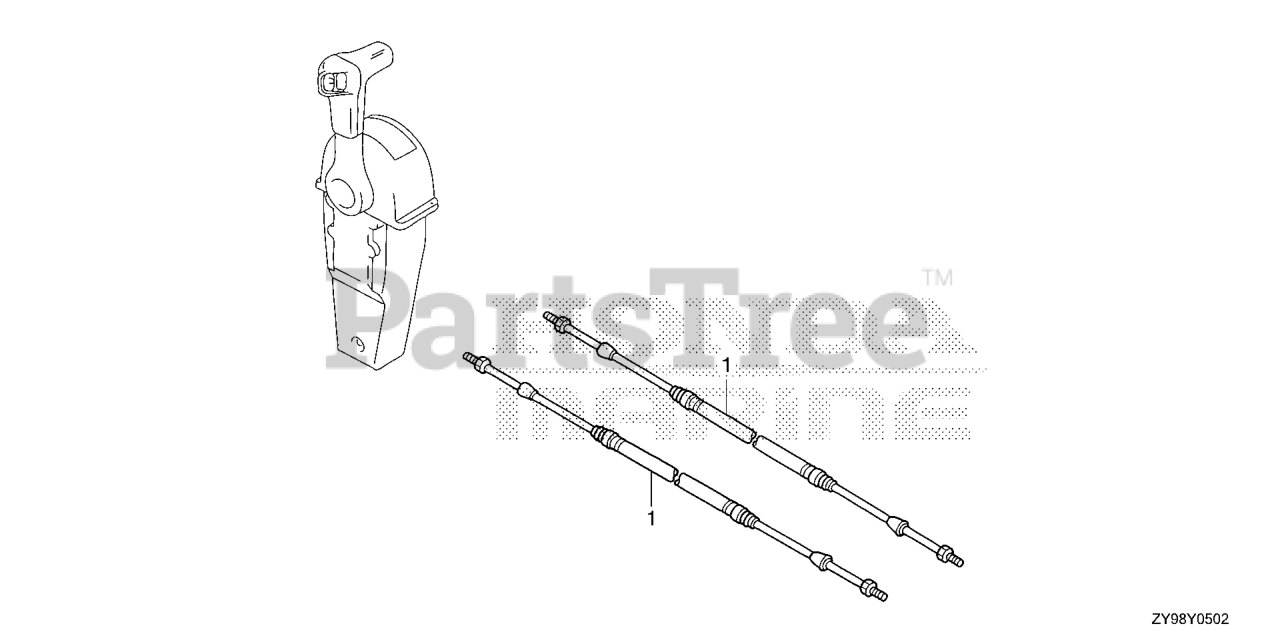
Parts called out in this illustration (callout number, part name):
1	CABLE ASSY., PUSH-PULL (33HPC-5FT)
1	CABLE ASSY., PUSH-PULL (33HPC-6FT)
1	CABLE ASSY., PUSH-PULL (33HPC-7FT)
1	CABLE ASSY., PUSH-PULL (33HPC-8FT)
1	CABLE ASSY., PUSH-PULL (33HPC-9FT)
1	CABLE ASSY., PUSH-PULL (33HPC-10FT)
1	CABLE, REMOTE CONTROL (10') (TELEFLEX)
1	CABLE, REMOTE CONTROL (10') (NOT AVAILABLE)
1	CABLE ASSY., PUSH-PULL (33HPC-11FT)
1	CABLE, REMOTE CONTROL (11') (TELEFLEX)
1	CABLE ASSY., PUSH-PULL (33HPC-12FT)
1	CABLE, REMOTE CONTROL (12') (TELEFLEX)
1	CABLE ASSY., PUSH-PULL (33HPC-13FT)
1	CABLE, REMOTE CONTROL (13') (TELEFLEX)
1	CABLE ASSY., PUSH-PULL (33HPC-14FT)
1	CABLE, REMOTE CONTROL (14') (TELEFLEX)
1	CABLE ASSY., PUSH-PULL (33HPC-15FT)
1	CABLE, REMOTE CONTROL (15') (TELEFLEX)
1	CABLE ASSY., PUSH-PULL (33HPC-16FT)
1	CABLE, REMOTE CONTROL (16') (TELEFLEX)
1	CABLE ASSY., PUSH-PULL (33HPC-17FT)
1	CABLE, REMOTE CONTROL (17') (TELEFLEX)
1	CABLE ASSY., PUSH-PULL (33HPC-18FT)
1	CABLE, REMOTE CONTROL (18') (TELEFLEX)
1	CABLE ASSY., PUSH-PULL (33HPC-19FT)
1	CABLE, REMOTE CONTROL (19') (TELEFLEX)
1	CABLE ASSY., PUSH-PULL (33HPC-20FT)
1	CABLE, REMOTE CONTROL (20') (TELEFLEX)
1	CABLE ASSY., PUSH-PULL (33HPC-21FT)
1	CABLE ASSY., PUSH-PULL (33HPC-22FT)
1	CABLE ASSY., PUSH-PULL (33HPC-23FT)
1	CABLE ASSY., PUSH-PULL (33HPC-24FT)
1	CABLE ASSY., PUSH-PULL (33HPC-25FT)
1	CABLE ASSY., PUSH-PULL (33HPC-26FT)
1	CABLE ASSY., PUSH-PULL (33HPC-27FT)
1	CABLE ASSY., PUSH-PULL (33HPC-28FT)
1	CABLE ASSY., PUSH-PULL (33HPC-29FT)
1	CABLE ASSY., PUSH-PULL (33HPC-30FT)
1	CABLE ASSY., PUSH-PULL (33HPC-31FT)
1	CABLE ASSY., PUSH-PULL (33HPC-32FT)
1	CABLE ASSY., PUSH-PULL (33HPC-33FT)
1	CABLE ASSY., PUSH-PULL (33HPC-34FT)
1	CABLE ASSY., PUSH-PULL (33HPC-35FT)
1	CABLE ASSY., PUSH-PULL (33HPC-36FT)
1	CABLE ASSY., PUSH-PULL (33HPC-37FT)
1	CABLE ASSY., PUSH-PULL (33HPC-38FT)
1	CABLE ASSY., PUSH-PULL (33HPC-39FT)
1	CABLE ASSY., PUSH-PULL (33HPC-40FT)
2	ADAPTER, REMOCON CABLE (N/A: USE 24931-ZW1-000)
